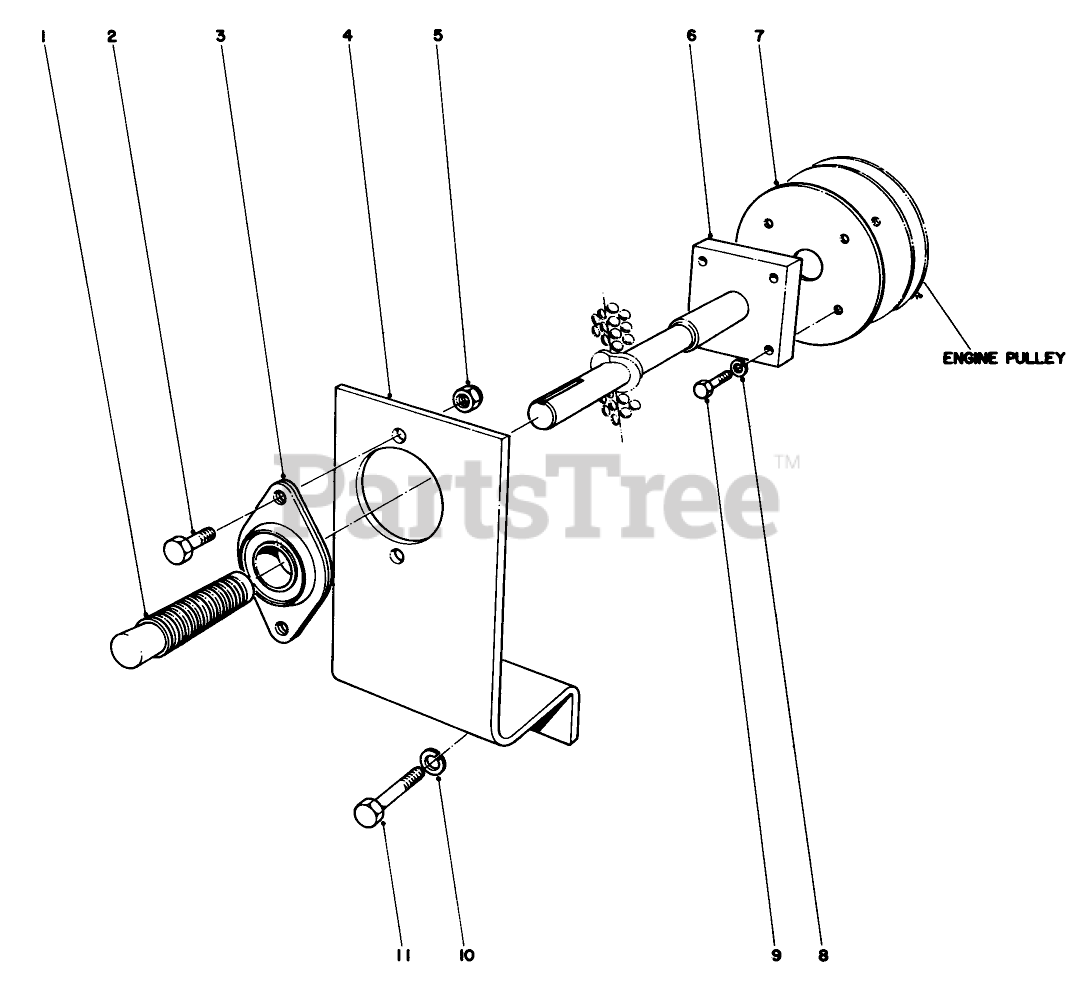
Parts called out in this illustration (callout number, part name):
1	Handle Grip
2	SCREW-HH
3	Bearing
4	PTO Brng. Mtng. Brkt.
5	NUT-LOCK, CONE
6	PTO Shaft W.A.
7	Grommet
8	WASHER-LOCK
9	SCREW-HH
10	WASHER-LOCK
11	SCREW-HH
